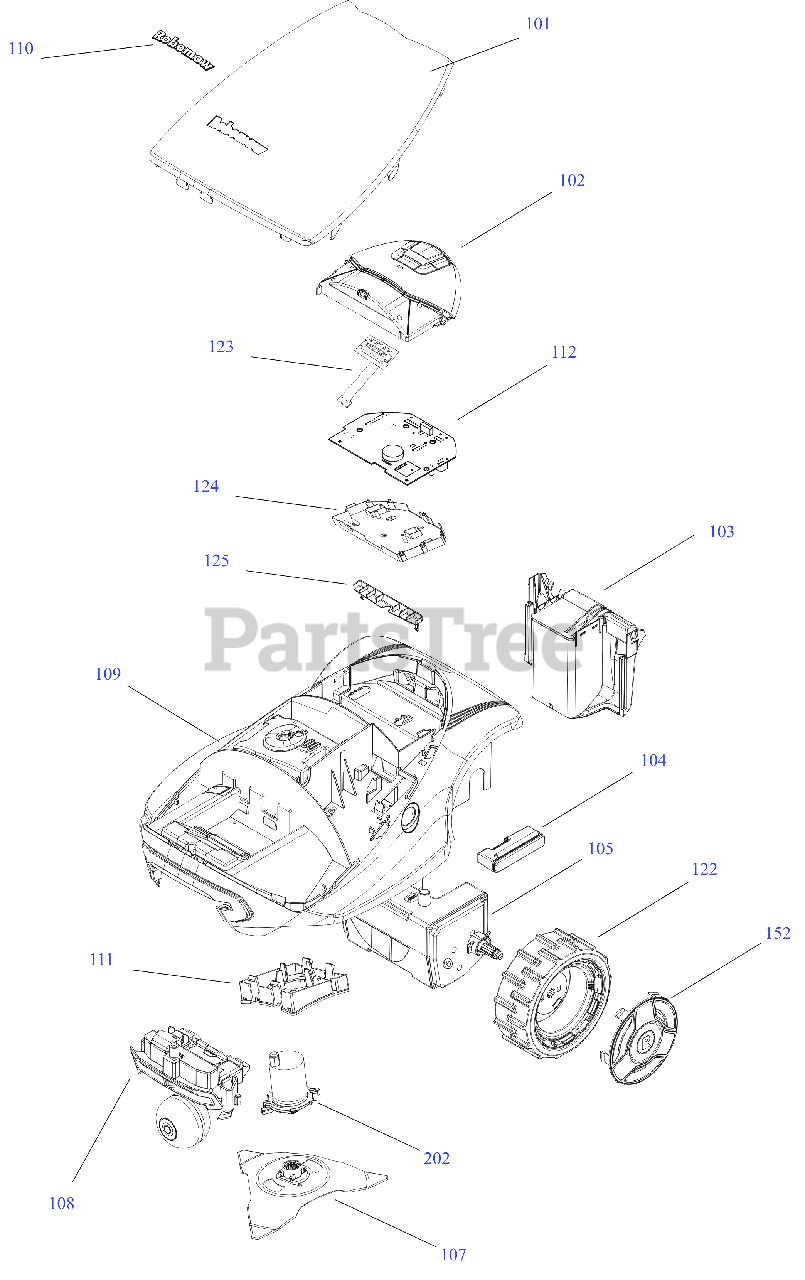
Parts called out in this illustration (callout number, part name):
102	RC PANEL ASSEMBLY W/O LCD DISPLAY
103	BATTERY (RC/TC/MC)
105	GEAR CASE ASSEMBLY
111	MOWING DECK FLANGE
117	FASTENING STAKES FOR BASE STATION
119	15M EXTENSION CABLE
121	RC MOW MOTOR CABLE BRUSH
123	RC LCD ASSEMBLY
124	C MAIN BOARD MULCH PROTECTOR
125	RC DRAIN PROTECTOR
126	RC SHELTER LEG RIGHT
127	RC SHELTER DOOR
128	RC SHELTER LEG RIGHT
129	RCSHELTER LEG LEFT
130	BASE STATION BOARD WITH BLE
133	ALARM STICKER
134	RC FRONT CABLE
135	RC MOW MOTOR CABLE BL
137	USB2RS232 UP TO WIN8
138	BLADE REMOVAL TOOL
139	PLOT CONNECTOR
140	ROBORULER FOR RC/TC/MC
152	RC PREMIUM TAS
154	PEGS-PACK OF 50
155	PERIMETER WIRE
203	POWER BOX HANGING
204	SCREW + "DIBEL" X 2 KIT
207	MINI JUMPER 2.54MM
208	STAKE-PERIMETER SW
210	PERIMETER SWITCH (ESB5009F)
211	BATTERY PACK-PERIM
212	PERIMETER SWITCH B
213	PERIMETER SWITCH STICKER
214	MOWING MOTOR ASSEMBLY (BRUSH)
